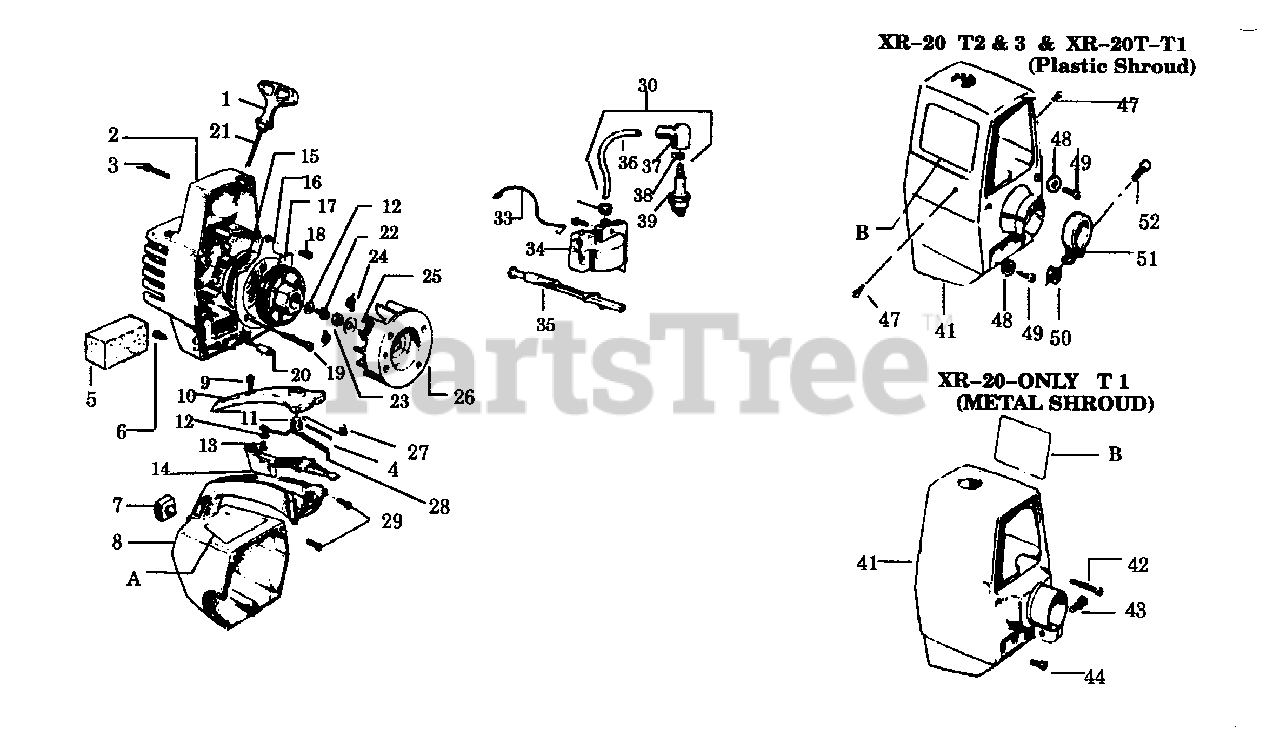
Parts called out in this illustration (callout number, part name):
1	Handle
2	Fan Housing Kit (Inc.16,18,19,20,45)
4	Switch Spring Insulation
5	Air Filter
7	Fuel Tank Housing Bumper
8	Handle & Fuel Tank Housing
10	Handle Cover
11	Kill Switch Button
12	Kill Switch Washer
14	Throttle Trigger
15	Starter Recoil Spring
16	Air Baffle
17	Starter Pulley
21	Rope Kit
23	Flywheel Nut
24	Starter Dog Spring
26	Flywheel Ass'y. (Inc.24)
27	Trigger Spring
28	Kill Switch Spring
29	Screw
30	High Tension Lead Ass'y. (Inc.36,37,38)
33	Lead Wire Switch
34	Module Kit
35	Choke Knob
36	High Tension Lead Wire
37	Spark Plug Boot
38	Spark Plug Lead Connector
39	Spark Plug
41	Model XR-20-T 1
41	Model XR-20-T 2 & 3; Model XR-20T-T 1
43	Pinch Clamp Bolt
A	Model XR-20-T1
A	Model XR-20-T 2
A	Model XR-20-T3; Model XR-20T-T1
B	Model XR-20-T1 & 2
B	Model XR-20-T3;
B	Model XR-20T-T1
B	Left
B	Model XR-20-T1 & 2 (Not a serviceable part)
